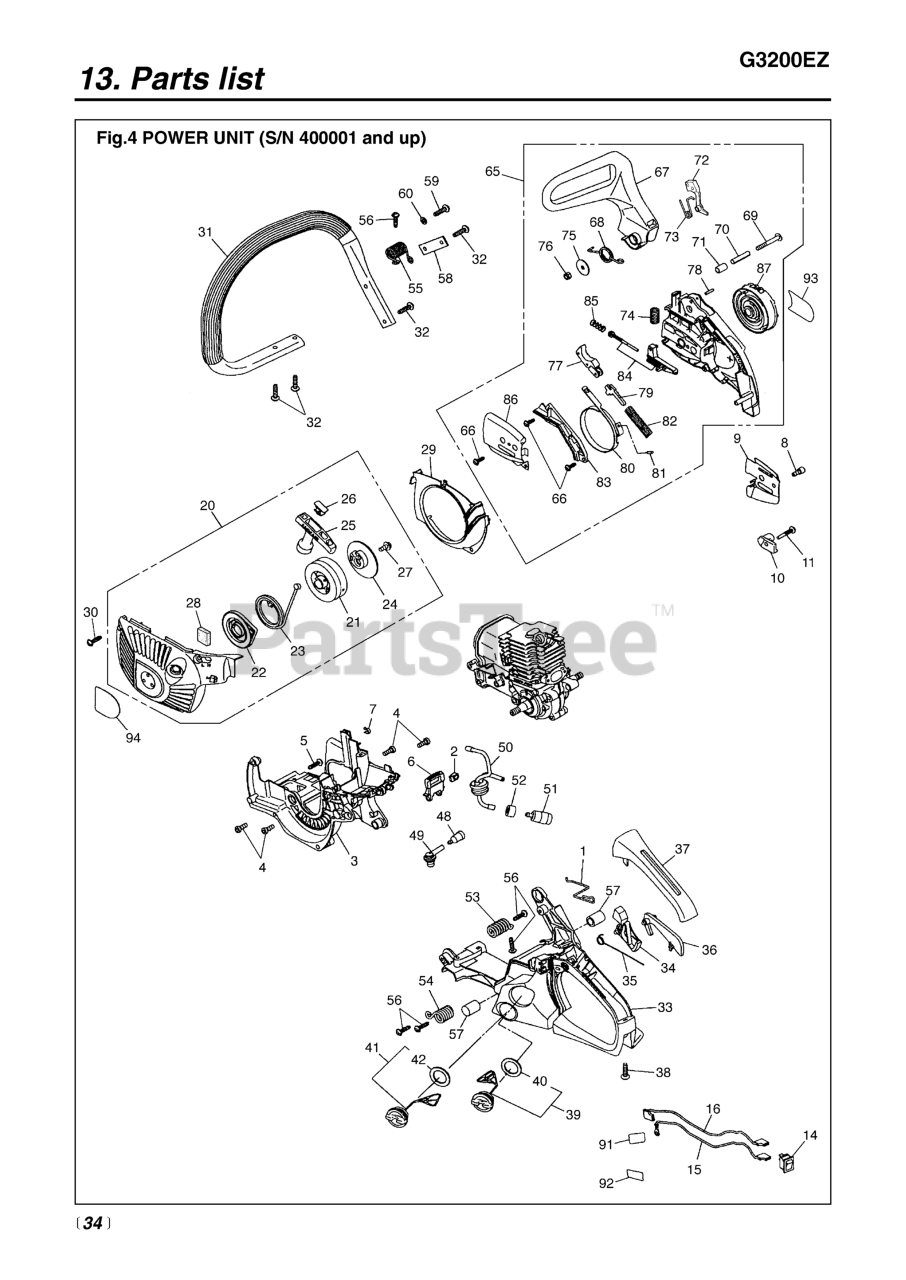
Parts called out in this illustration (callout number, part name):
4	SCREW
5	SCREW
6	KNOB
8	BOLT
10	CATCHER
11	SCREW
14	SWITCH ASSEMBLY
15	CORD EARTH
16	CORD SWITCH
20	STARTER ASSY.
21	REEL COMP
22	SPRING COMPLETE
25	KNOB
30	SCREW
32	SCREW (RPLS. 2671-32110)
33	HANDLE COMP
35	SPRING
36	ARM (REPLACES 3356-33352)
37	COVER
38	SCREW
39	CAP ASSY.
40	GASKET
41	CAP ASSEMBLY
42	GASKET
48	BREATHER ASSEMBLY
50	PIPE ASSY
51	5500-85400 (RRLS. 1750-85300)
53	SPRING F
54	SPRING M
55	SPRING
56	SCREW (RPLS. 2671-32110)
58	BAND
59	SCREW
60	WASHER
65	BRAKE ASSY
66	SCREW
68	SPRING, RETURN
71	SPACER (RPLS -54210)
72	WEIGHT
75	WASHER (RPLS -75410)
76	NUT (B)
77	LEVER, BRAKE COMPLETE
79	ARM, SLIDE(RPLS 2670-54410)
81	PIN
82	SPRING, BRAKE (RPLS. 50030121)
86	PLATE,GUIDE(B)
93	LABEL, COVER
94	LABEL, RECOIL
